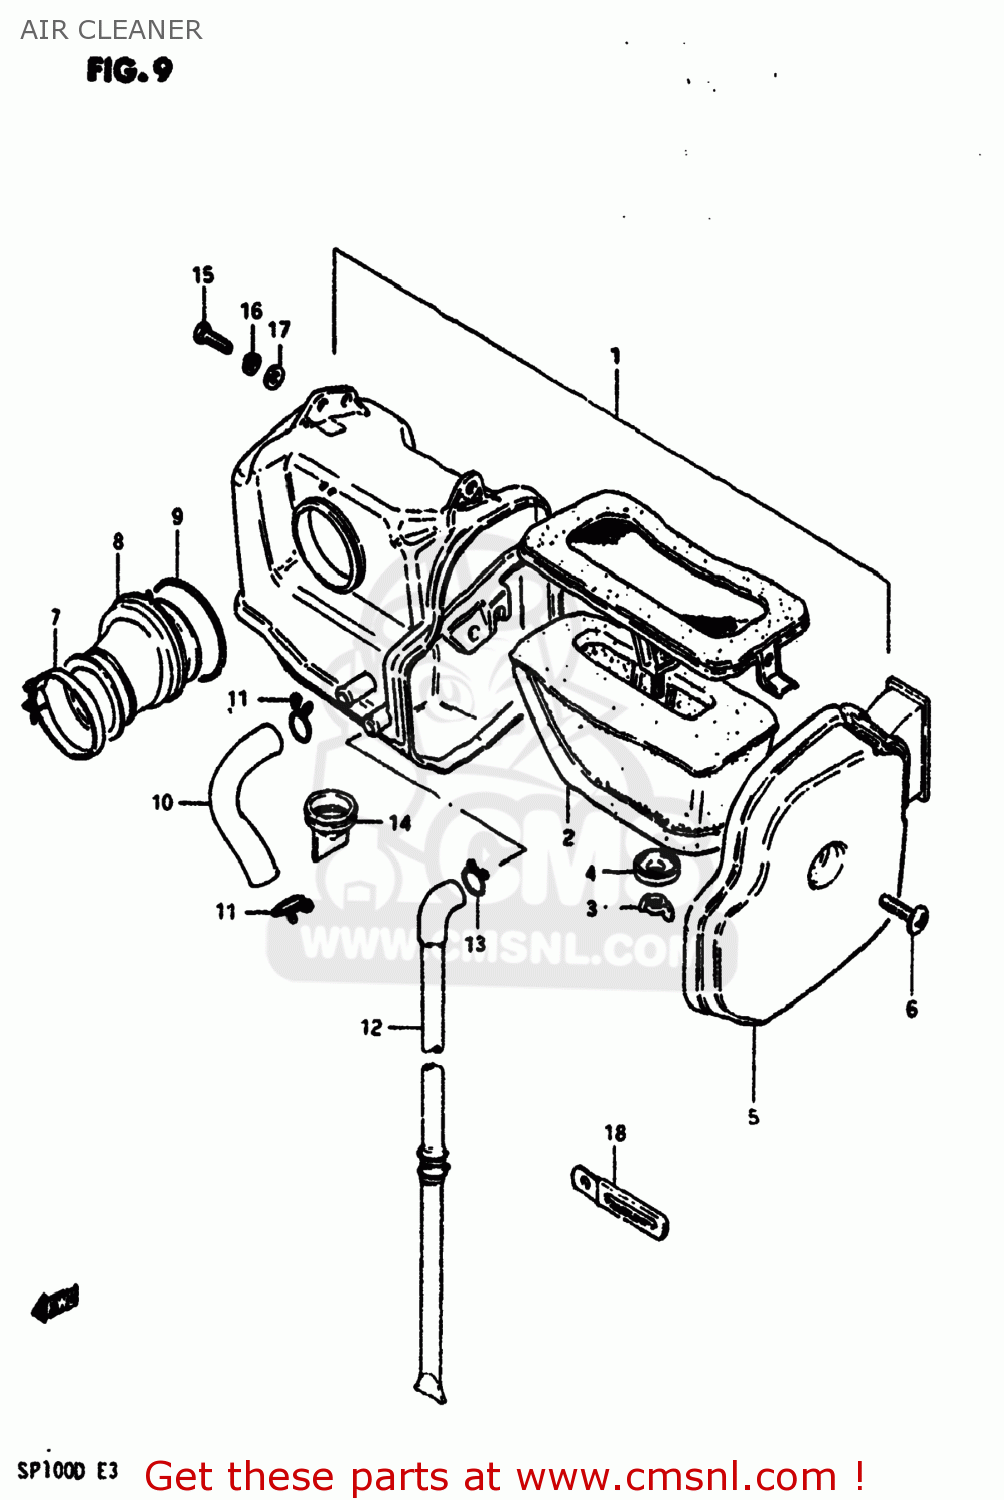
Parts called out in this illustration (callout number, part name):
1	CLEANER ASSEMBLY,AIR
2	ELEMENT,AIR CLEANER
3	NUT
4	WASHER
5	CAP,AIR CLEANER
6	SCREW, COVER SIDE
7	CLAMP
8	TUBE,OUTLET
9	CLAMP,CLEANER SIDE
10	TUBE,AIR CLEANER BREATER
11	CLAMP
12	HOSE,AIR CLEANER DRAIN
13	CLAMP
14	DRAIN TUBE
15	BOLT, UPPER
16	LOCK WASHER
17	WASHER
18	CLAMP
